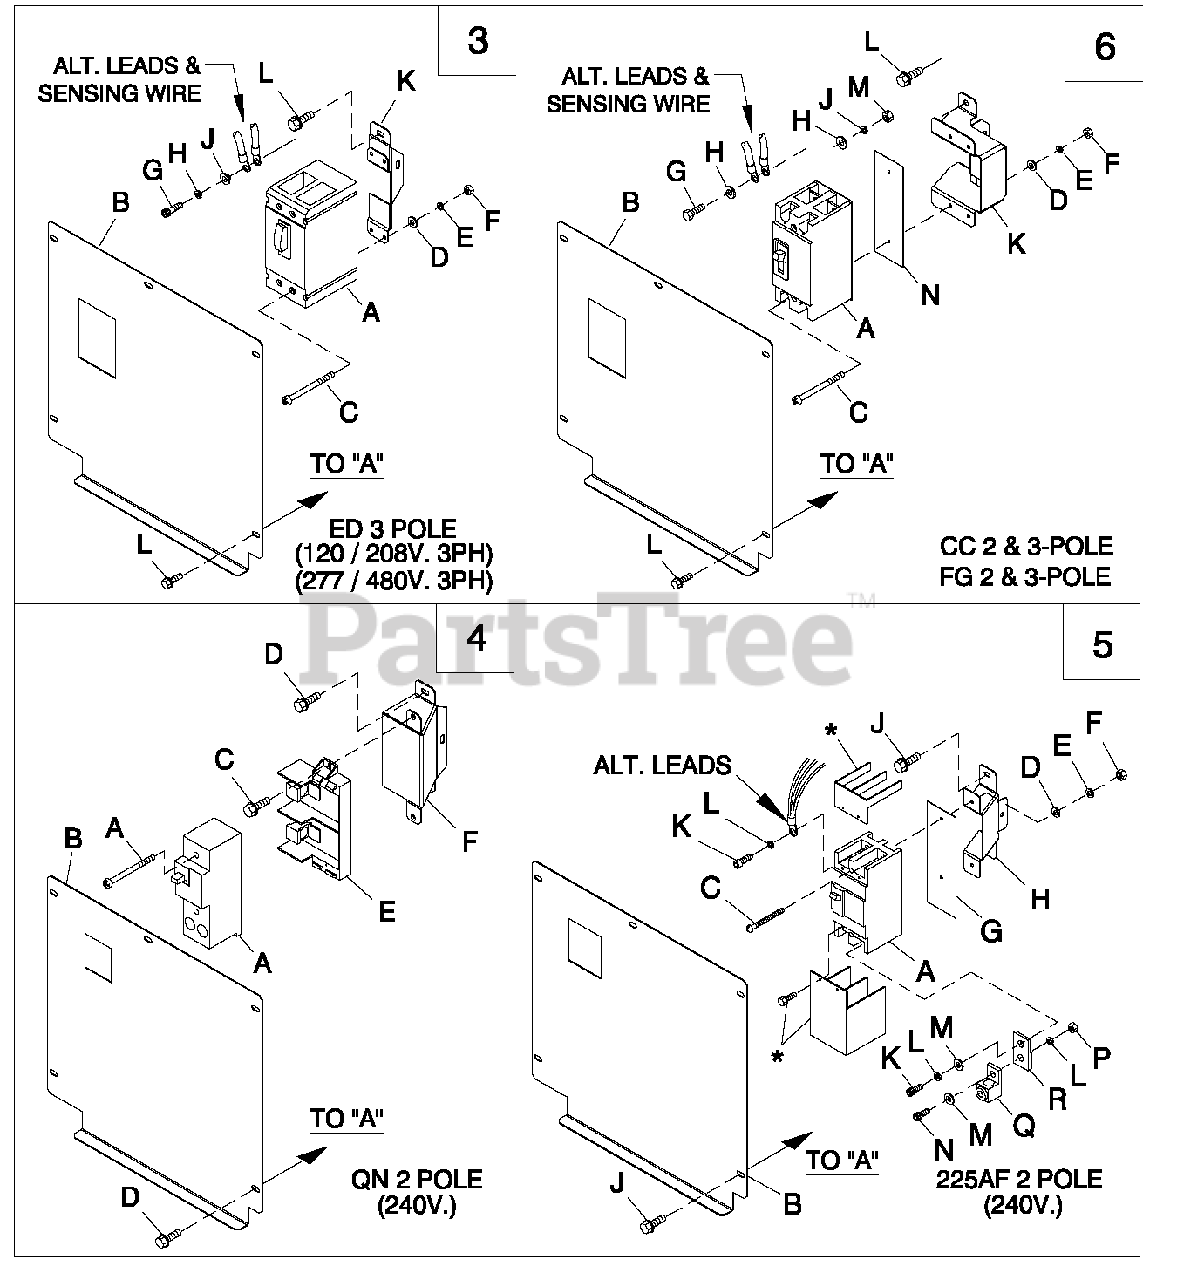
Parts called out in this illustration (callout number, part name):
A	CB0030A3P 480V S ED 4 LL
B	CB COVER 20-30K3P (ED)
C	SCREW RH M #8-32X4-1/2
D	WAS HER FLAT #8 ZINC
E	WAS HER LOCK #8-M4
F	NUT HEX #8-32 STEEL
G	SCREW S H C 1/4-28 X 3/4 G8.8 NZ
H	WAS HER LOCK M6-1/4
J	WAS HER-STEP 1/2ODX9/32ID BRASS
K	CIRCUIT BREAKER SUPPORT (ED)
L	SCREW HW HTF M6-1.0X 16
A	CB0150A2P 240V SQN2 LL
B	CON BOX FRONT COVER 1.6L QN 2P
C	SCREW H HTT M5-0.8X 10 BP
D	SCREW HW HTF M6-1.0X 16
E	BASE, QN CIRCUIT BREAKER
F	BREAKER SUPPORT BRACKET 30KW
A	CB 150A2 POLE 240V 225AF
B	CB COVER 30KG 225AF
C	SCREW RH M #8-32X3-1/4
D	WAS H ER FLAT #8 ZINC
E	WAS H ERLOCK#8-M4
F	NUTH EX #8-32 STEEL
G	INSULATOR CB2P 225AF
H	CIRCUIT BREAKER SPPRT G 225AF
J	SCREW HW HTF M6-1.0X 16
K	SCREWS H C M8-1.25X20G8
L	WAS H ERLOCK M8-5/16
M	WAS H ER FLAT 5/16-M8 ZINC
N	SCREW S H C M8-1.25 X 25 G12.9
P	NUT H EX M8-1.25 G8 CLEARZINC
Q	LUG SLDLSS 300 MCM-6 AL/CU
R	BUS BAR 200A LUG ADAPTOR
A	CB0100A 2P 240V ECC LL
B	CB COVER 20-30K 1P (CC)
C	SCREW RH M #8-32 X 3-1/4 (CC ONLY)
G	SCREW PP HM M5-0.8X 12ZNC
H	WAS H ER FLAT #10 ZINC
J	WASHERLOCK M5
K	CIRCUIT BREAKER SUPPORT (CC)
M	NUT H EX M5-0.8 G8 CLEARZINC
N	INSULATOR CB 2P E TYPE CC (CC ONLY)
